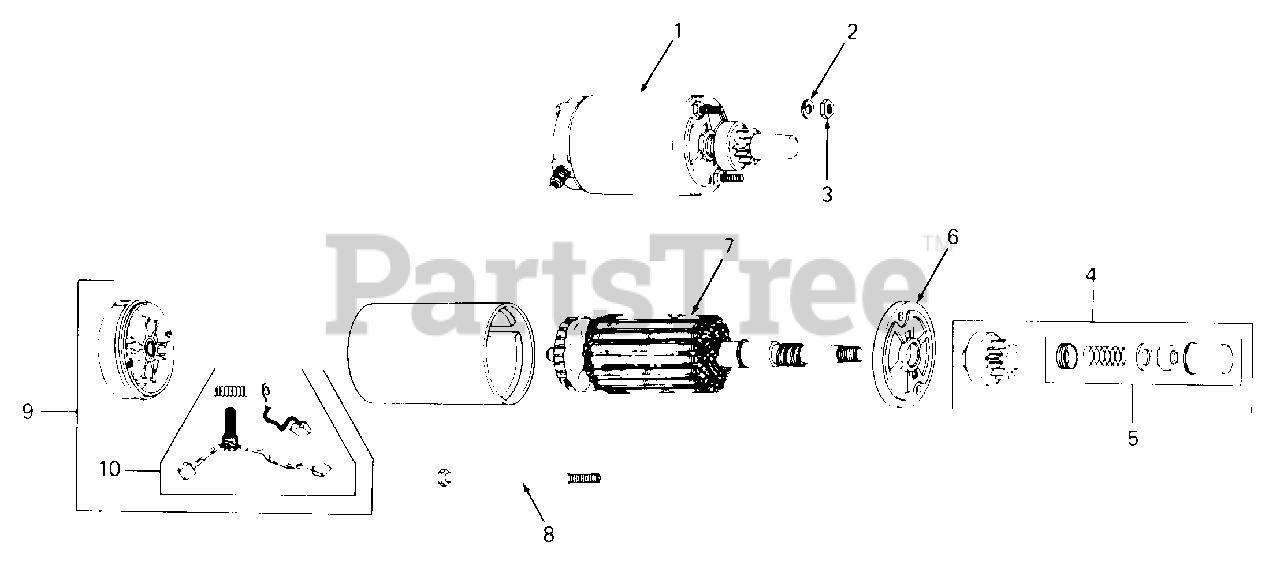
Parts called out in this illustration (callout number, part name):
1	Starter Assembly
2	Washer, Lock, 1/4
3	Nut, Hex, 1/4-20
4	Kit, Drive
5	Kit, Drive Parts
6	Cap, Drive End
8	Bolt, 1/4-20 X 5.87 Lg
9	Cap, Commutator End
10	Kit, Brush
